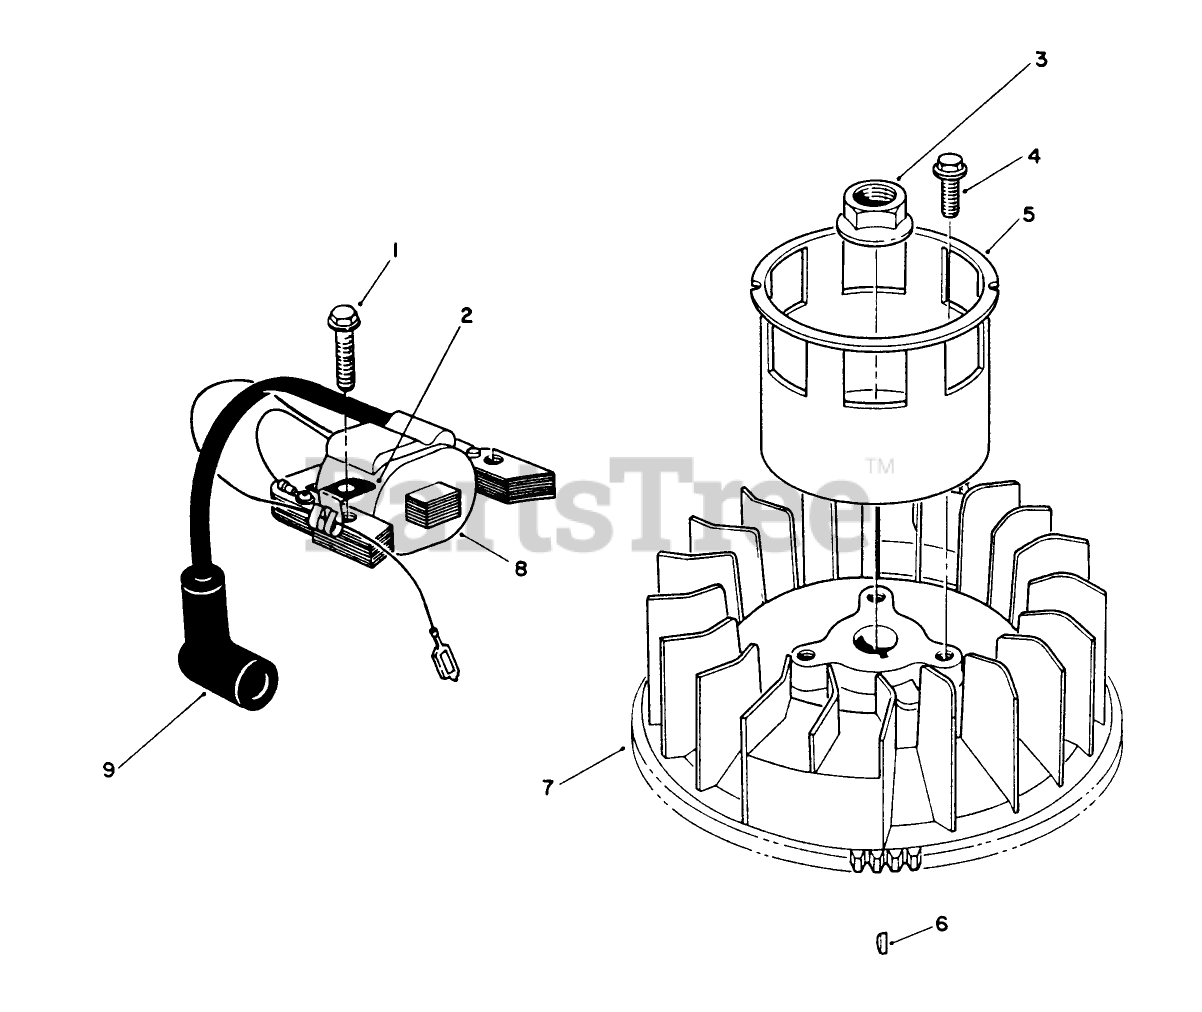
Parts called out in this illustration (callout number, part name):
2	CLAMP
7	FLYWHEEL
8	COIL ASM
9	COVER
